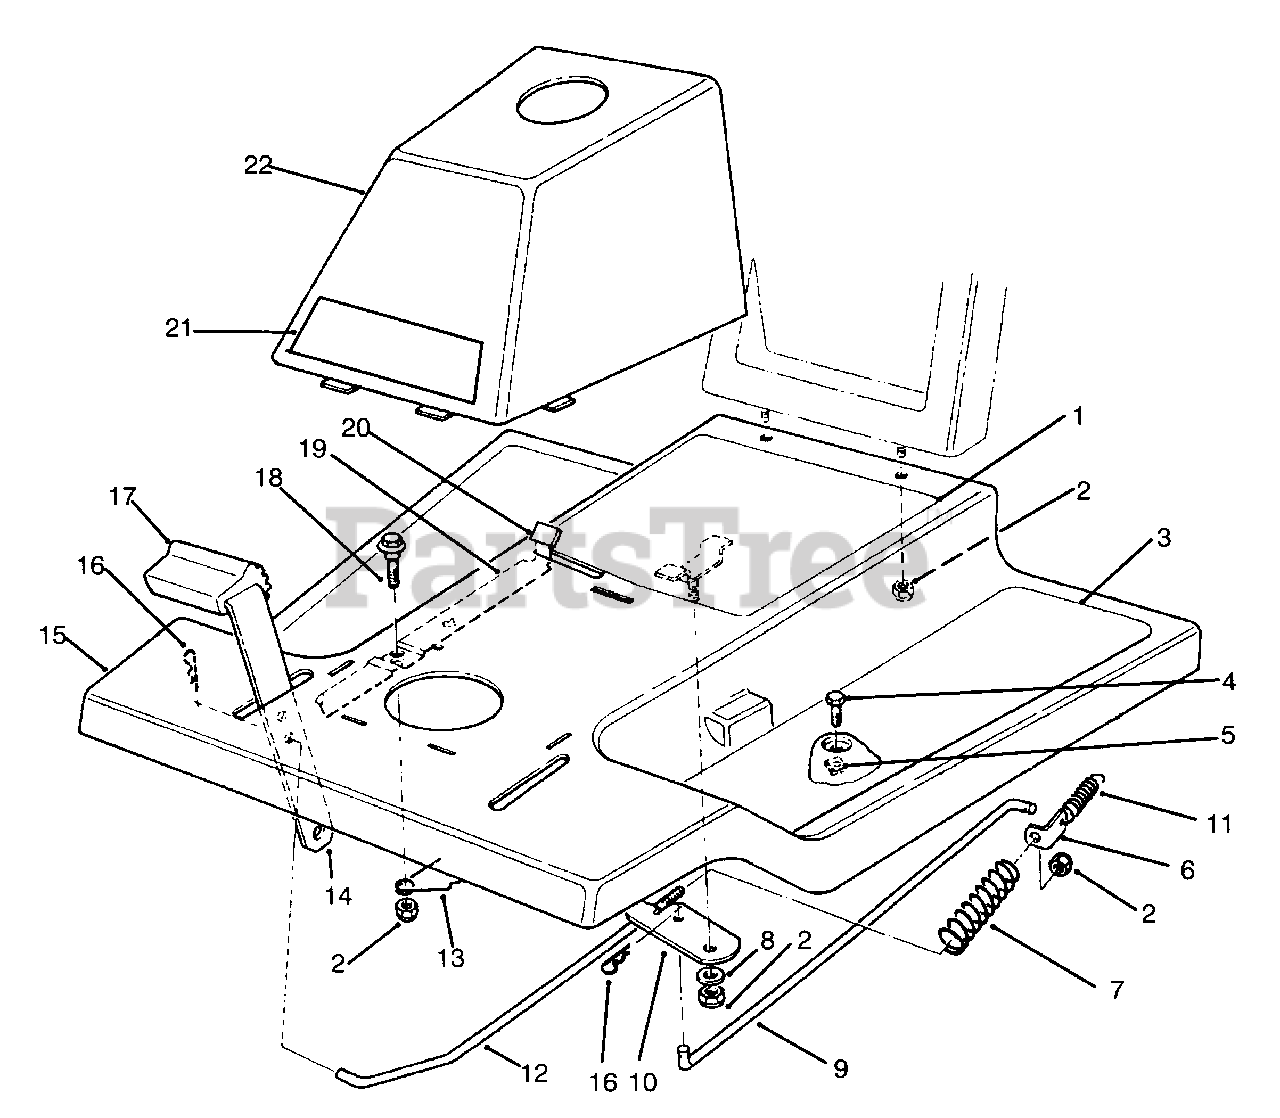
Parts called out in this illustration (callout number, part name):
1	Decal-Instruction
2	Nut-Lock
3	Tread-Foot Rest
4	Screw-Cap Hex. Hd.
5	Nut-U-Type
6	Bracket-Brake Return
7	Spring-Compression
8	Washer-Pivot
9	Rod-Brake, Transmission
10	Lever-Brake, Bellcrank
11	Spring-Extension
12	Rod-Front, Brake
13	Spring-Brake, Parking
14	Pedal-Brake & Clutch
15	Body W.A.-Front
16	Pin-Hair, Cotter
17	Pad-Pedal
18	Bolt-Shoulder
19	Lever-Brake, Parking
20	Tip-Brake, Parking
22	Tower (Incl. Ref. #21)
